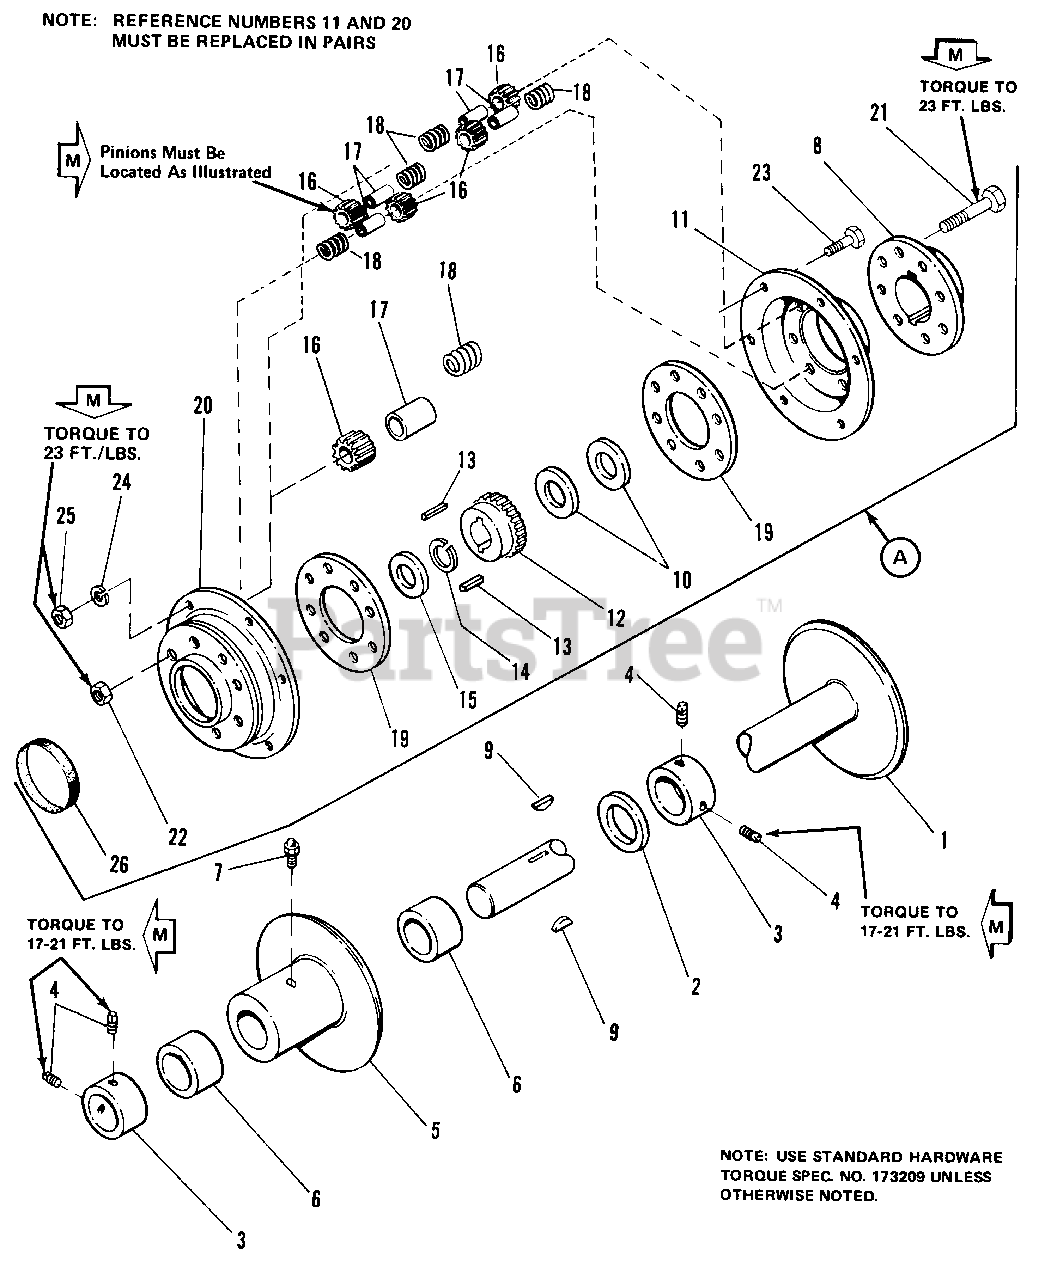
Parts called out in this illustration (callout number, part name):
1	REAR AXLE ASSEMBLY
3	COLLAR, Set
4	SETSCREW, Sq. Hd., 5/16-18 x 3/8
5	R.H. WHEEL HUB ASSEMBLY
7	FITTING, Grease
8	CARRIER, Diff.
10	WASHER, Axle
11	COVER, Diff.
12	GEAR, Diff.
13	KEY, Hi Pro, 1/4 x 3/4
14	RING, Retaining
15	WASHER, Axle
16	PINION, Diff.
17	SPINDLE, Diff. Pinion
19	RING, Spacer
20	COVER, Diff.
21	CAPSCREW, Hex Hd., 3/8-16 x 2-1/2
22	NUT, Hex, 3/8-16
23	CAPSCREW, Hex, 1/4-20 x 5/8
24	LOCKWASHER, 1/4
25	NUT, Hex, 1/4-14
26	SEAL, Cover
